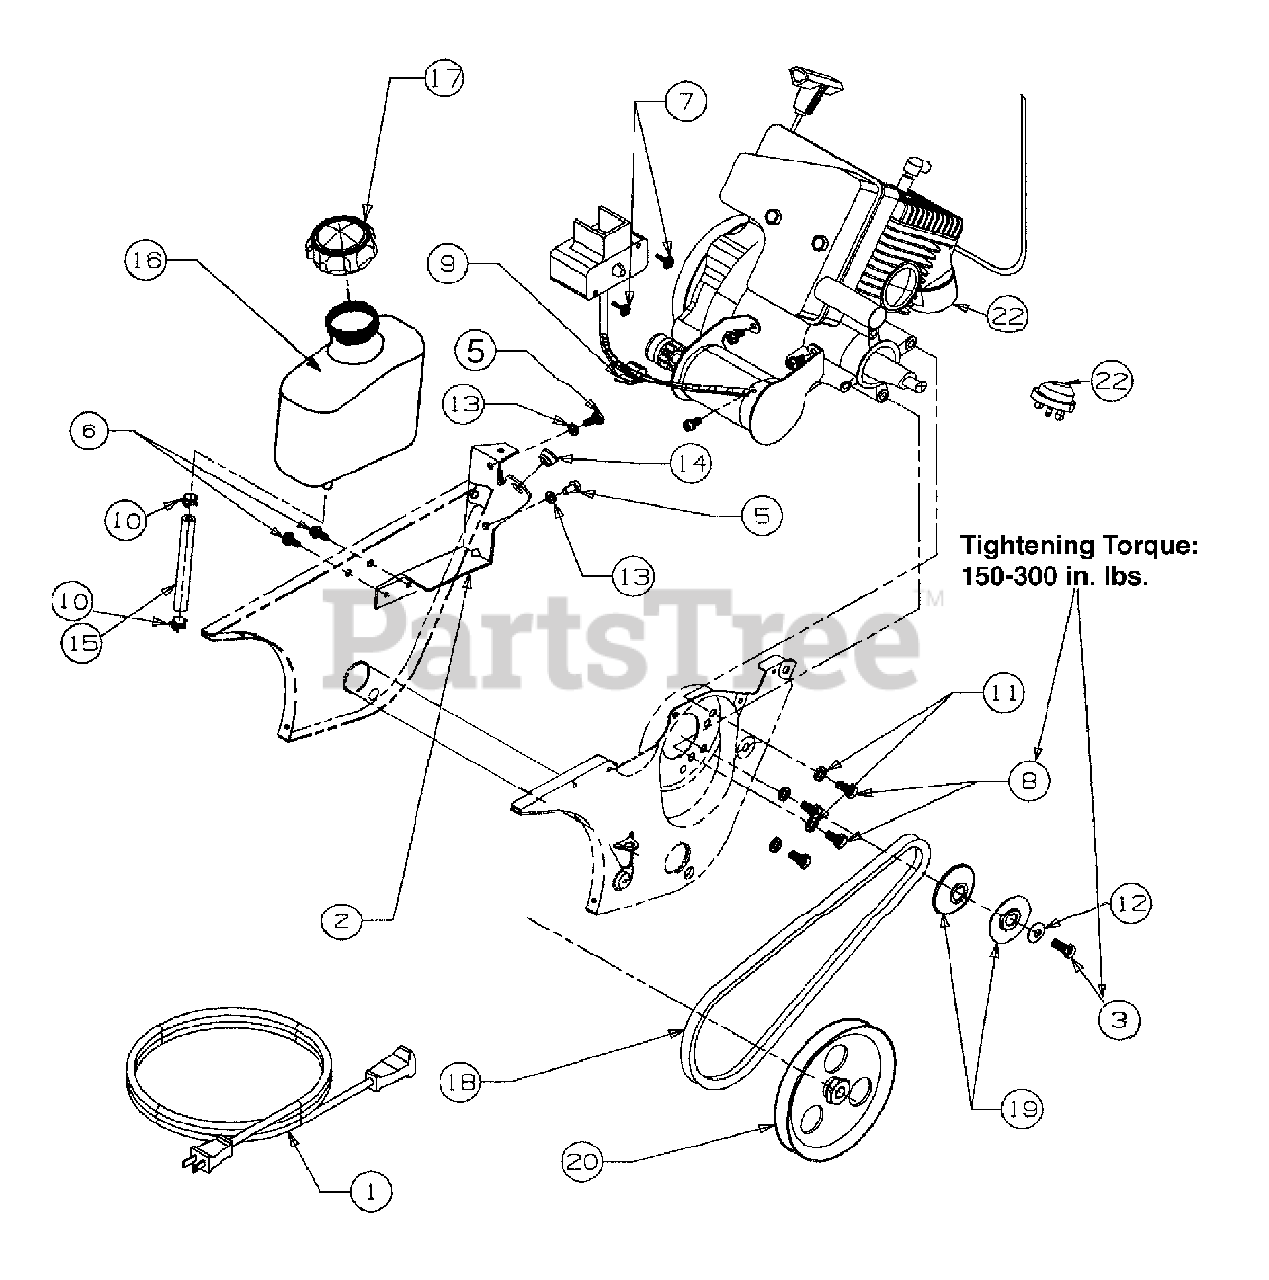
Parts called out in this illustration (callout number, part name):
1	Extension Cord
2	Support Bracket, Fuel Tank
3	Hex Cap Screw
5	Hex Screw
6	Washer Screw
7	Hex Screw
8	Hex Cap Screw
9	Mounting Clamp
10	Hose Clamp
11	Lock Washer
12	Bell Washer
13	Lock Washer
14	Plastic Bushing
15	Hose, Fuel Line-16"
16	Fuel Tank-2 qt.
17	Fuel Tank Cap
18	V-Belt
19	V-Pulley Half
20	Pulley
22	Obtain from engine manufacturer
